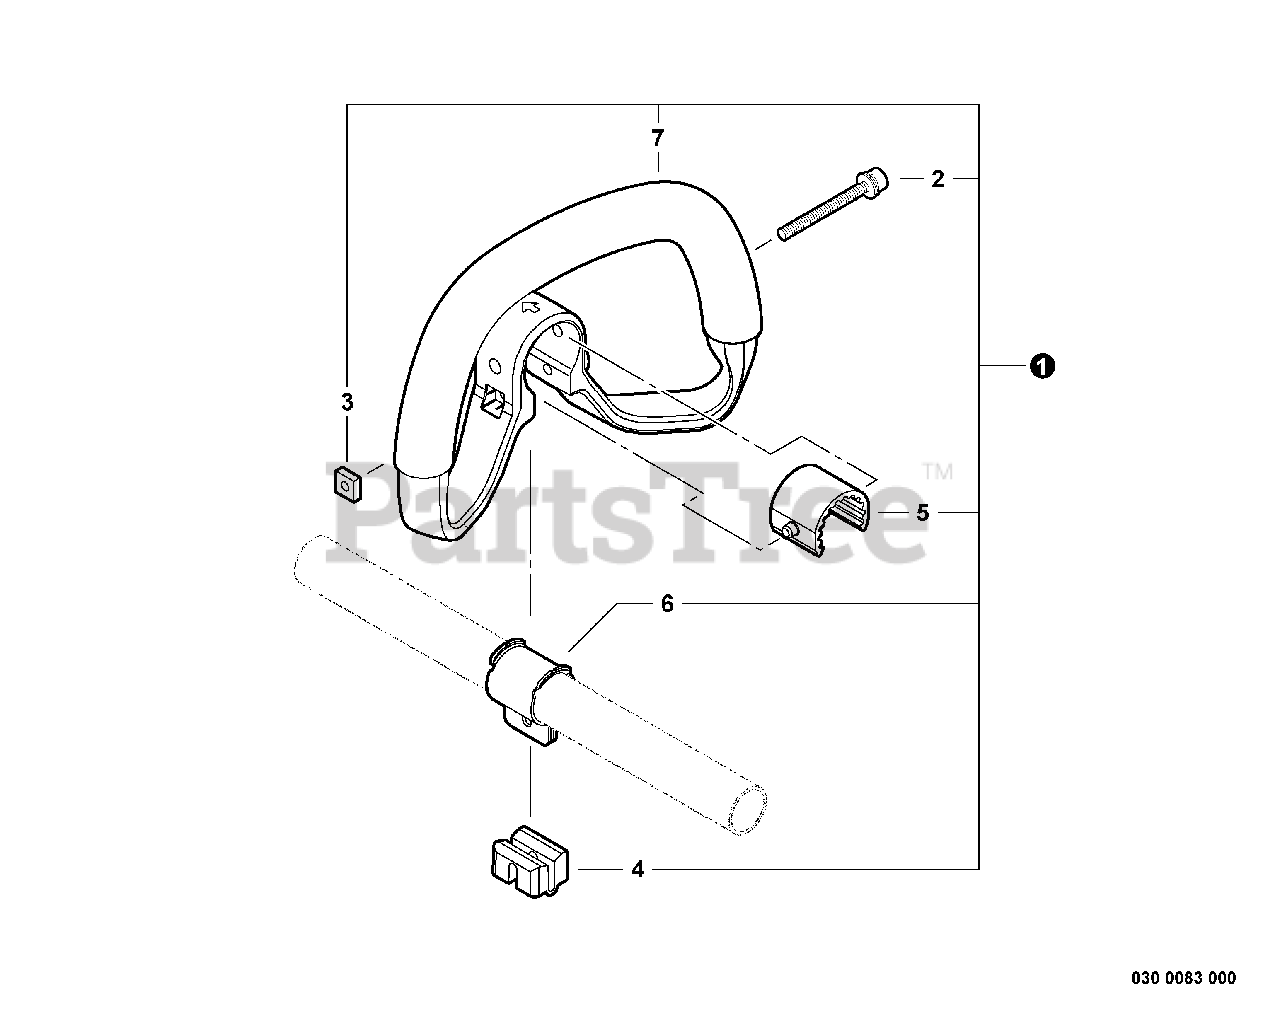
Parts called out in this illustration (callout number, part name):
1	HANDLE ASSY - SUPPORT
2	BOLT, TORX 5×40
5	CUSHION
6	BRACKET, MOUNTING
7	HANDLE, SUPPORT
